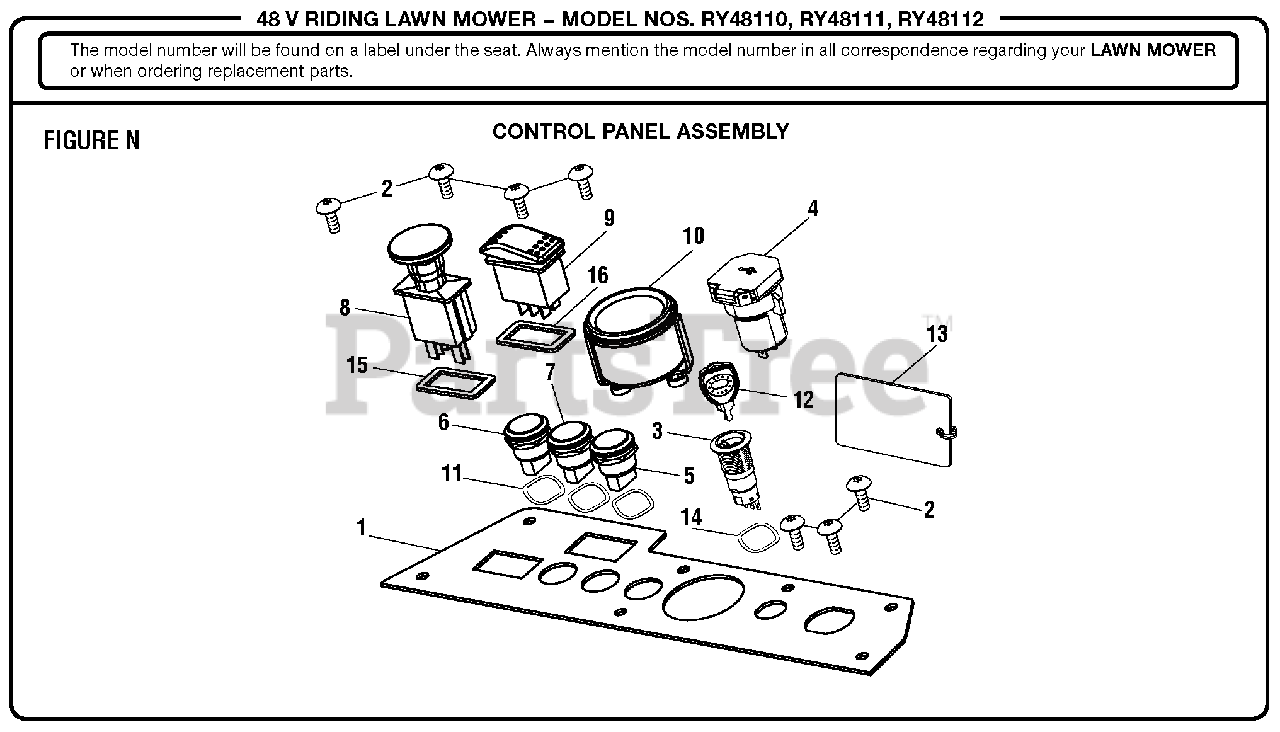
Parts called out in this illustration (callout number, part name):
1	Face Plate
2	Screw (M6 x 10 mm, Soc. Button Hd.)
3	Switch Key Module
4	USB Module
5	Light Switch
6	Cruise Button
7	Reverse Mow Operation Button
8	Power Take Off Button (PTO)
9	Toggle Switch
10	Gauge Module
11	Wavy Washer
13	Warning Tag
14	Wavy Washer
15	Rubber Gasket
